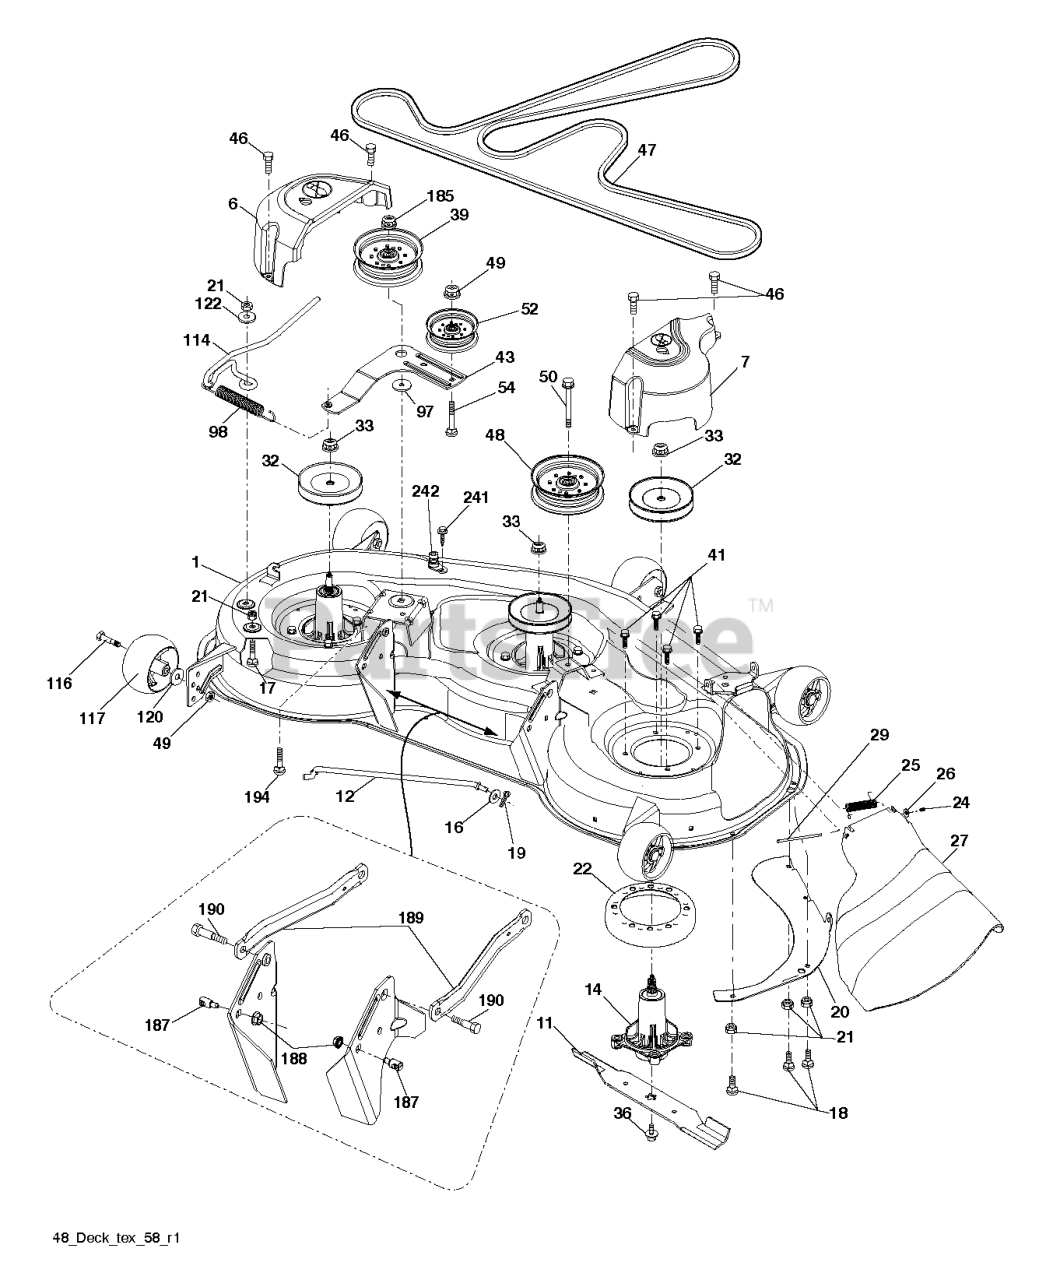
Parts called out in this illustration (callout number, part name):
1	DECK SVC 48" 4GWB.GREY
6	COVER.MANDREL.LH.48"(2 2)
7	COVER.RH.MANDREL
11	48" HI-LIFT BLADE
12	ROD.ANTI.SWAY.48/54"K4
14	KIT.MANDREL.GREASEABLE.TALL
18	BOLT ROUND HEAD SQUARE NECK BO
19	PIN.COTTER.5/16.BOW TI
20	BAFFLE, VORTEX MWR
22	STRIPPER.MANDREL.ROUND.BLACK
24	CAP-SLEEVE LT
25	SPRING, TORSION
26	NUT PUSH M
27	DEFLECTOR SUBS TO 532 180655
32	PULLEY MANDREL
36	SCREW.SEMS.7/16-20X1.HEX.HEAD
39	RB PULLEY.IDLER.4.50/HUB SPEC
41	BOLT.HEX.WASHR.HED.313-18X1.19
46	SCREW.1/4-20X5/8
47	Belts- 197242
48	PULLEY.IDLER.2006
49	NUT LOCK FLG 3/8-16 UNC
50	SCREW TT 3/8-16X2.31 UNC
50	SCREW TT 3/8-16X2-1/4 UNC
52	PULLEY.IDLER.48"PRIMARY
54	GSPW Bolts
98	SPRING, DECK DRIVE
114	ROD.TENSION.RELIEF.TEX (2 2)
117	WHEEL.GAUGE.RALLY
122	BUSHING.RELIEF.TENSION
185	NUT.LOCK.FLANGE.7/16
187	STUD.W/"D"ANTI-ROTATION
189	ARM.RFIXED.MOWER.SUSPNSIONX431
190	BOLT.SHOULDER
194	BOLT.HEX.WASHER.HEAD.7/16-24X
241	SCREW.TT.#10-32X.5.3/8.FLANGE
242	PORT.WASHOUT
